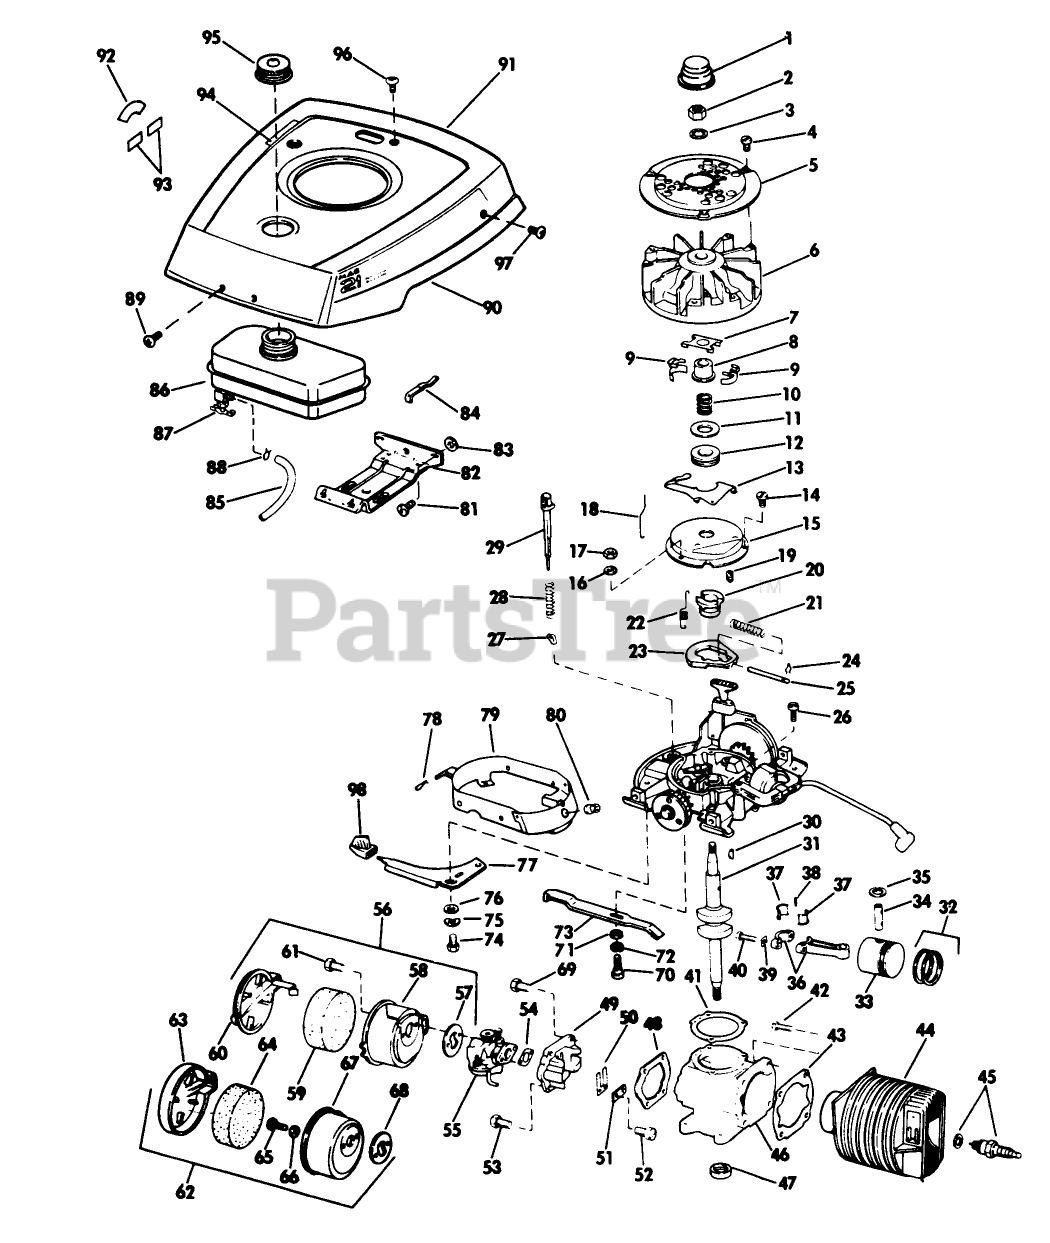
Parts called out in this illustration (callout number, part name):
8	COLLAR S
10	SPRING S
12	THRUST COLLAR S
13	LEVER-GOVERNOR S
14	SCREW S
15	DUST COVER S
20	SPARK ADV. S
21	SPARK ADV. SPRING S
23	FLYWEIGHT S
24	SPARK ADJ. SPRING
25	PIN,SPARK ADV. S
28	SPRING S
35	RING-RETAINING
37	LINER ASM
41	GASKET S
43	GASKET S
51	PLATE-BACKUP, REED
53	SCREW S
54	GASKET S
57	GASKET S
59	AIR FIL.ELEM S
61	SCREW S
63	CHAMBER AY S
64	AIR FIL.ELEM S
65	SCREW S
67	FILTER CHAMBER S
68	GASKET S
69	SCREW S
72	Spring Washer
80	NUT-CLIP
81	SCREW S
85	GAS LINE
87	VALVE&SCREEN SM
88	CLAMP - HOSE S
96	SCREW F
97	SCREW S
